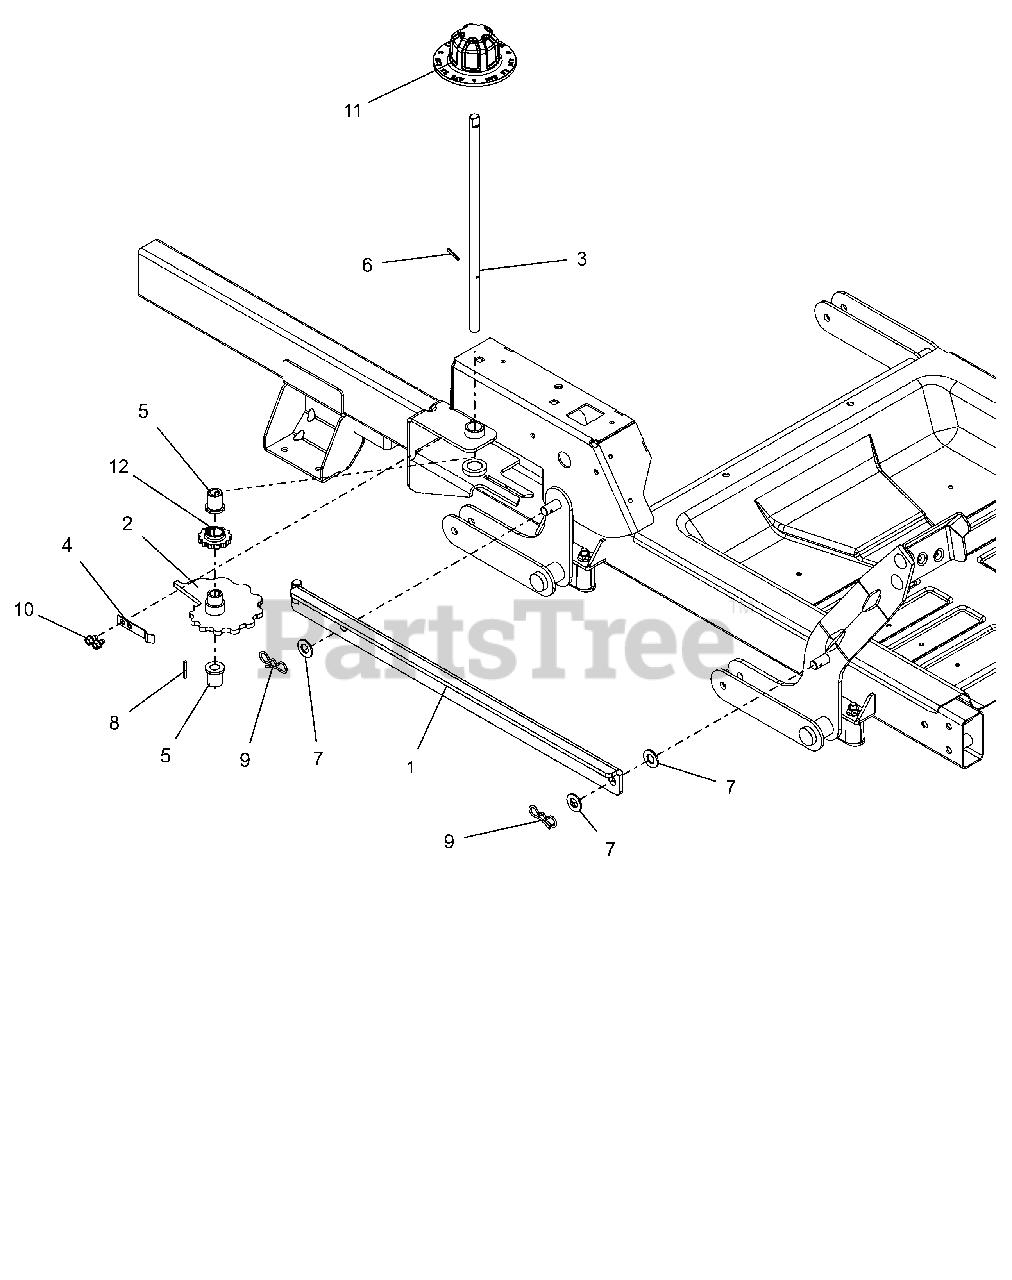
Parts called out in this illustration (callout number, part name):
1	WLDMT, HOC LINK
2	WLDMT, HOC CAM
3	SHAFT, HOC CAM
4	ARM, HOC DETENT
5	BSHG-FLG, .503X.750X.875X1.00
6	PIN-ROLL .125X1.00
7	WSHR-FL-NYL .518X1.000X.080
8	KEY, 1/8 X 1/8 X 1.0
9	PIN,BOW TIE LOCKING .091X1.875
10	@SCR-TAP .25-20X.37 HWH YWZ TR
11	KNOB, HOC
12	GEAR, HOC INDEX
